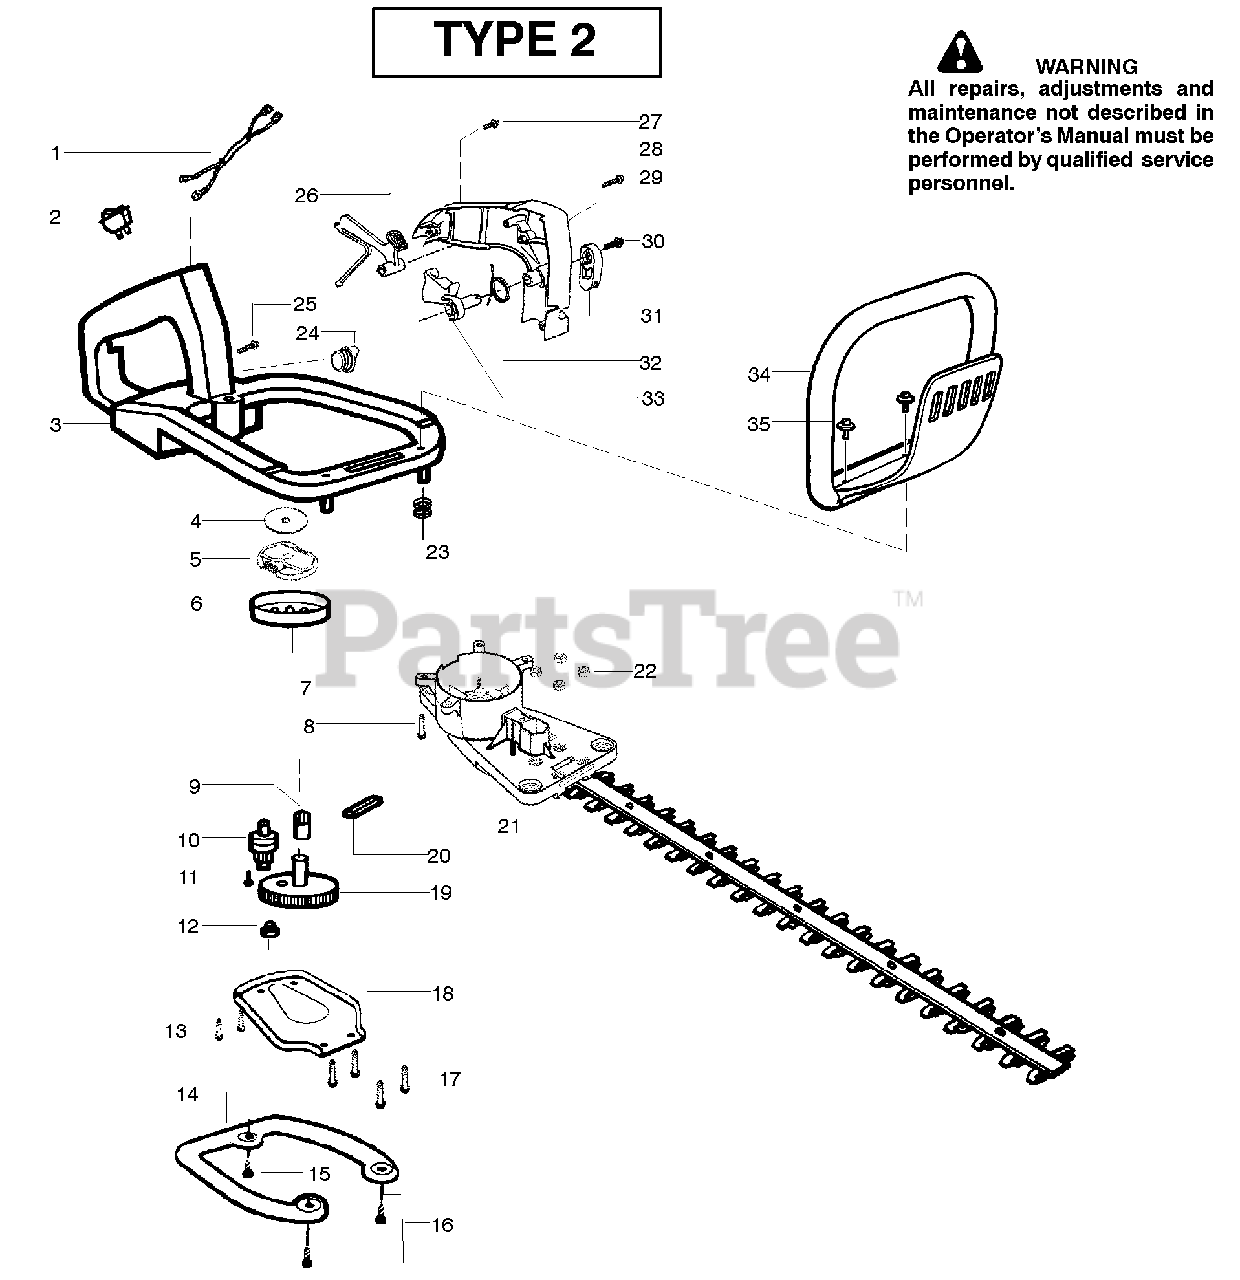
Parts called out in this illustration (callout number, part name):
1	Assy-Leadwire/Switch
2	Switch-Ignition
3	Assy-Rear Handle & Tank
4	Washer-Clutch (Kit)
5	Assy-Clutch (Kit)
6	Drum-Clutch (Kit)
7	Assy-Gear Box
9	Bearing-Gear
10	Assy-Pinion
11	Screw
12	Bushing-Blade
14	Plate-Isolator
18	Cover-Gear Box Plate
19	Kit-Drive Gear Ass'y.
20	Seal-Blade (Felt)
21	Assy-Blade 22"
24	Assy-Fuel Cap
26	Lockout-Throttle
28	Cover-Handle
31	Lever-Trigger
32	Spring-Trigger
34	Handle-Front
